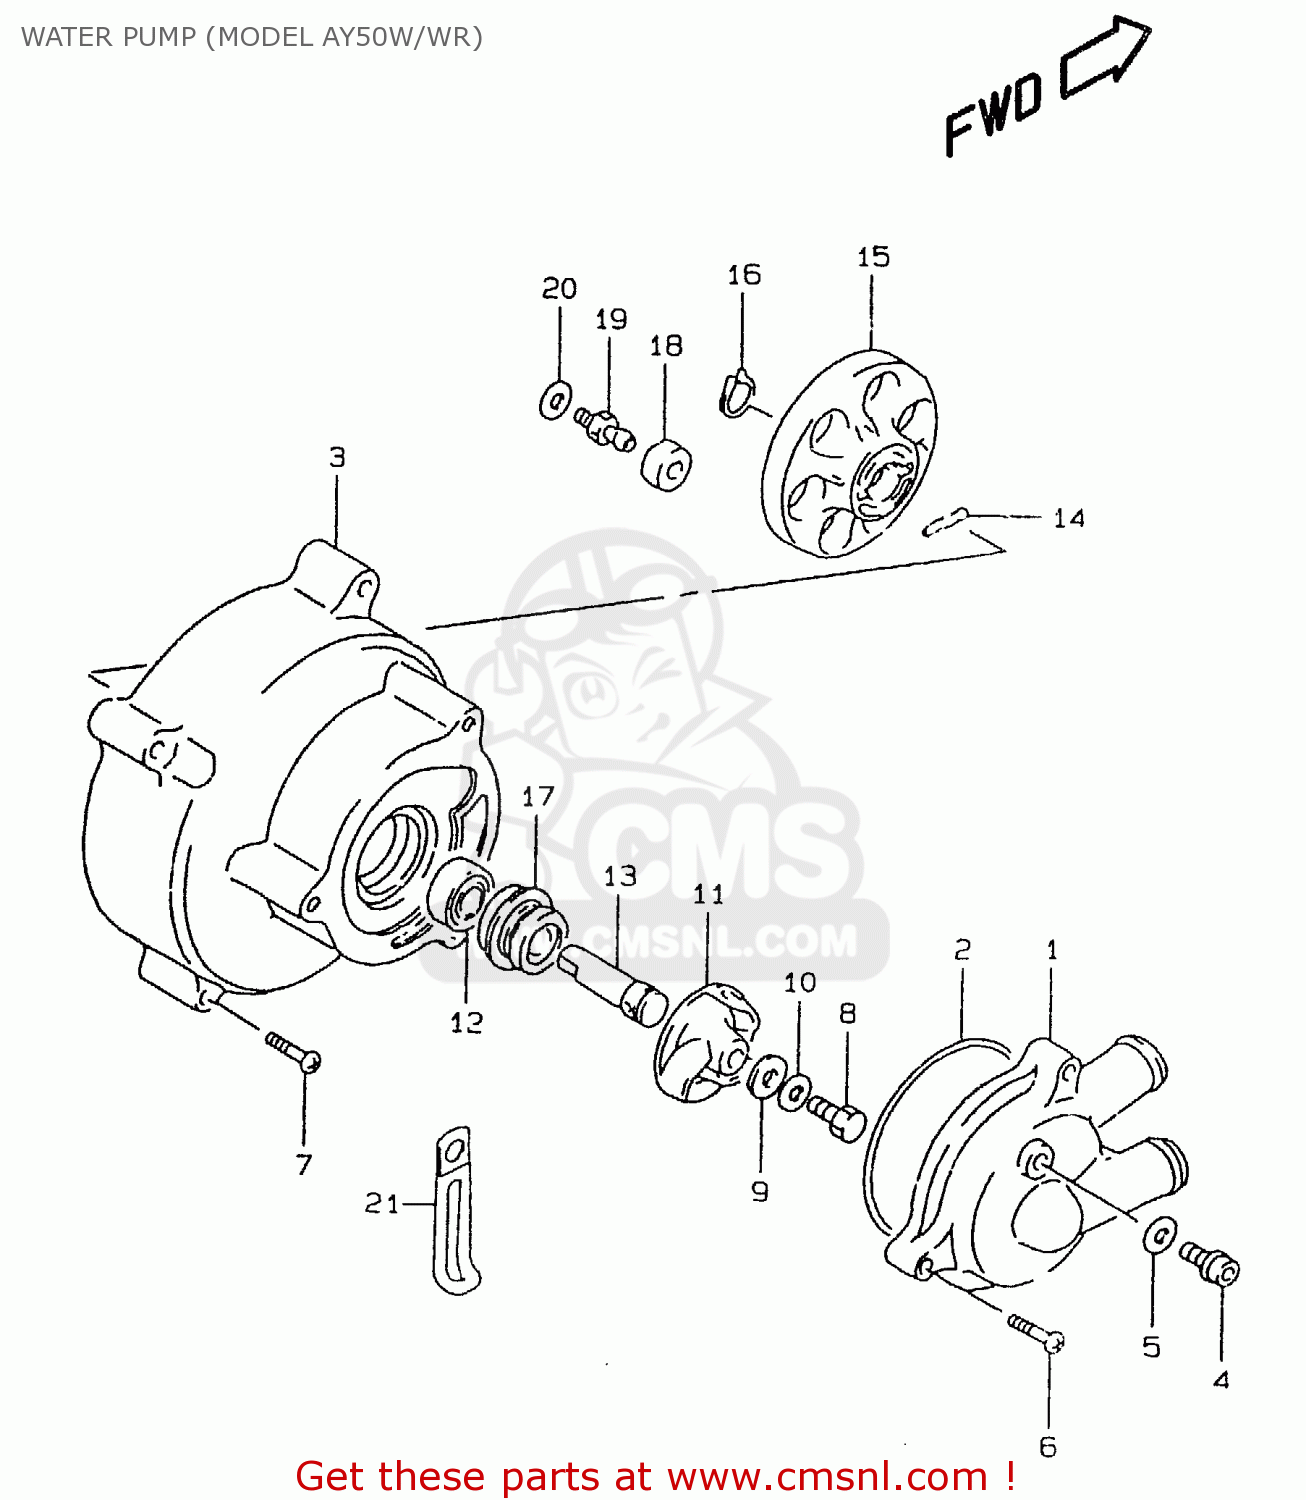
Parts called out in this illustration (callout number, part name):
1	CASE,W/P OUTER
2	O RING(D:2.1,ID:65)
3	CASE,W/P INNER
4	UNION
5	GASKET(6.2X11X1).2 (NAS)
6	SCREW
7	SCREW
8	BOLT(6X13)
9	GASKET (NAS)
10	WASHER
11	IMPELLER,WATER PUMP
12	BEARING
13	SHAFT,W/PUMP
14	PIN(2.5X19.8)
15	JOINT
16	CIRCLIP,12 MM
17	SEAL,MECHANICAL
18	CUSHION
19	BOLT
20	LOCK WASHER
21	CLAMP
